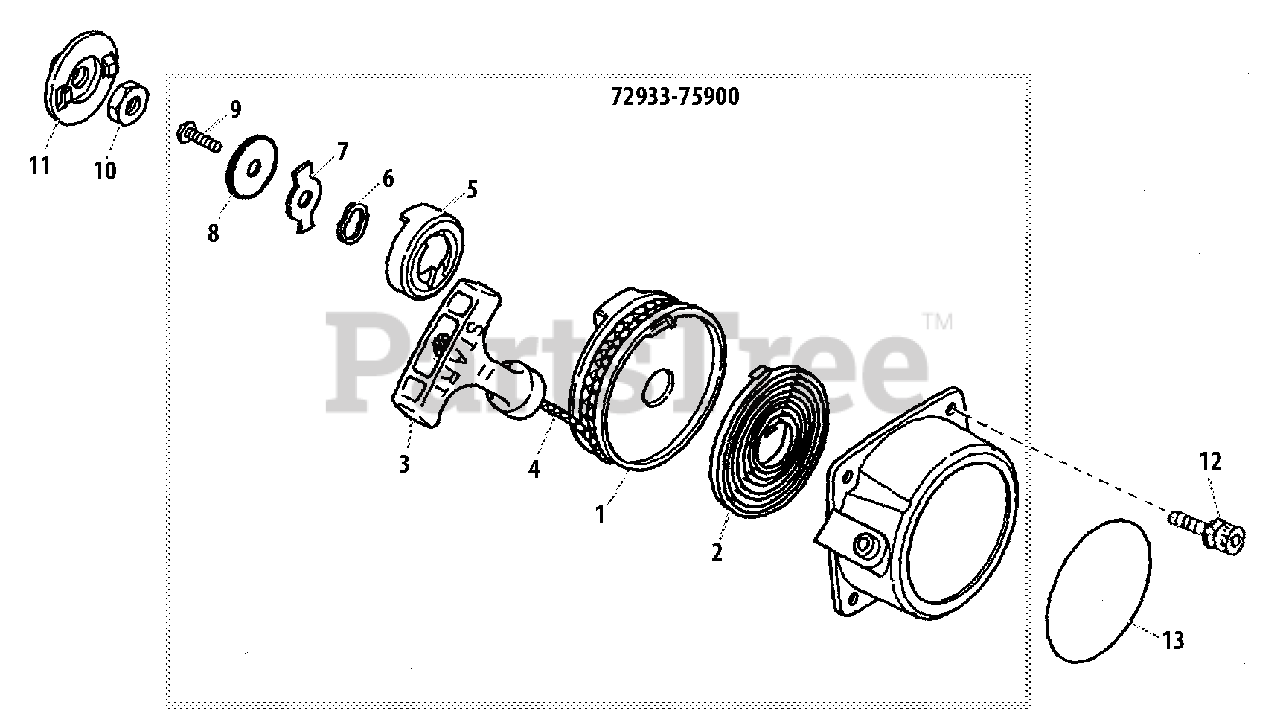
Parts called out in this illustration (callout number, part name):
1	REEL, ROPE
2	SPRING, REWIND
3	GRIP, STARTER
4	ROPE, STARTER
5	PAWL, STARTER
6	WASHER - SPRING
7	RETAINER
8	WASHER - 5
9	SCREW - 5
10	NUT - 8
11	PAWL
12	SCREW - 4X12
13	LABEL - SHINDAIWA PROFESSIONAL
72933-75900	STARTER ASSY
